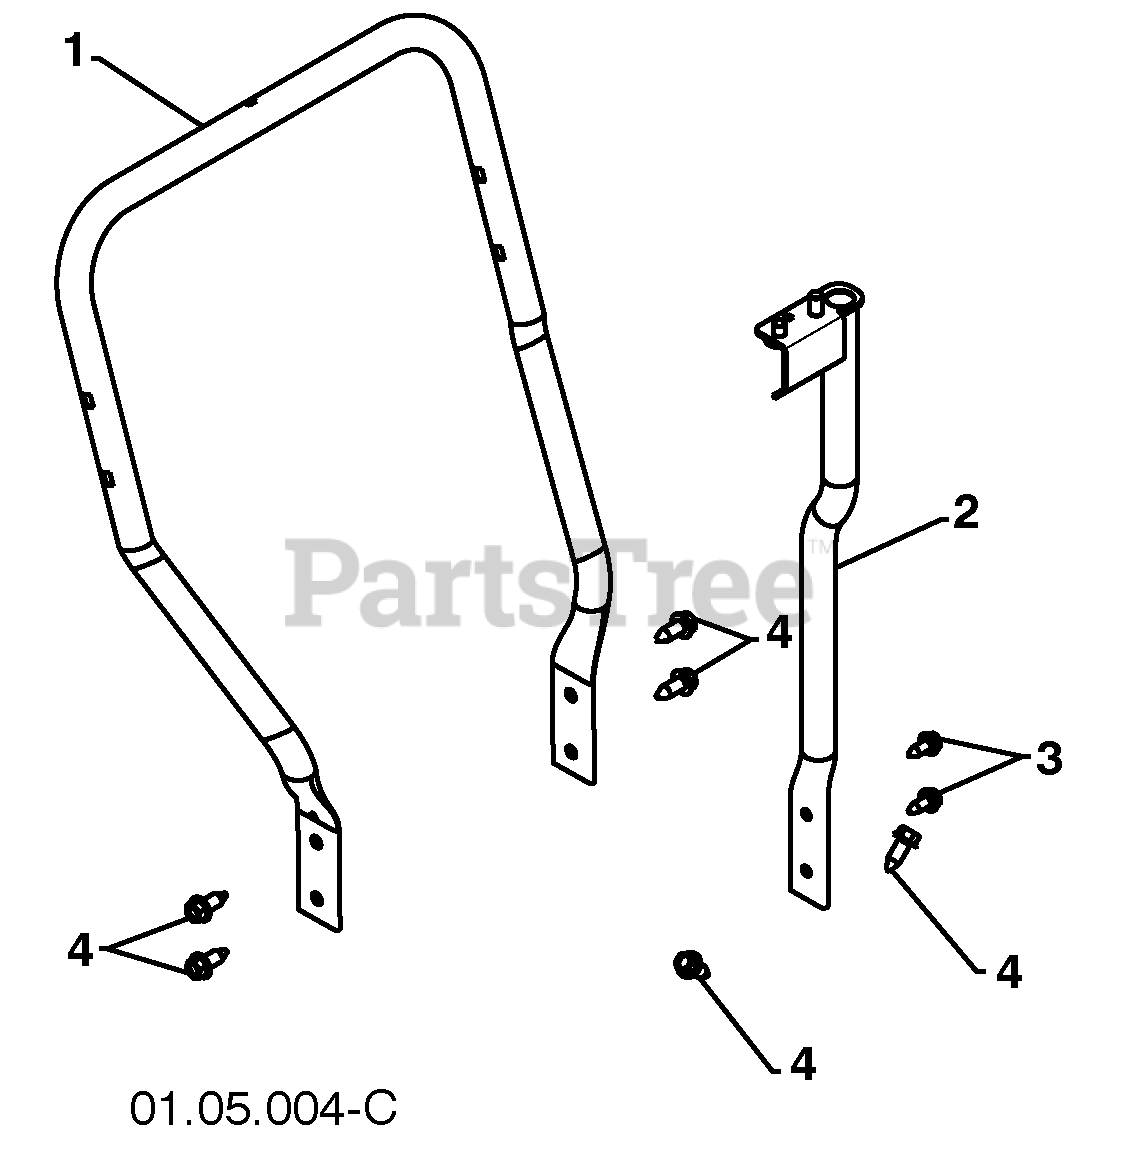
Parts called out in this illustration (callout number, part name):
1	LOWER TUBE
3	BOLT 5/16-18 X .750
4	SCREW 3/8-16 X 1.00
